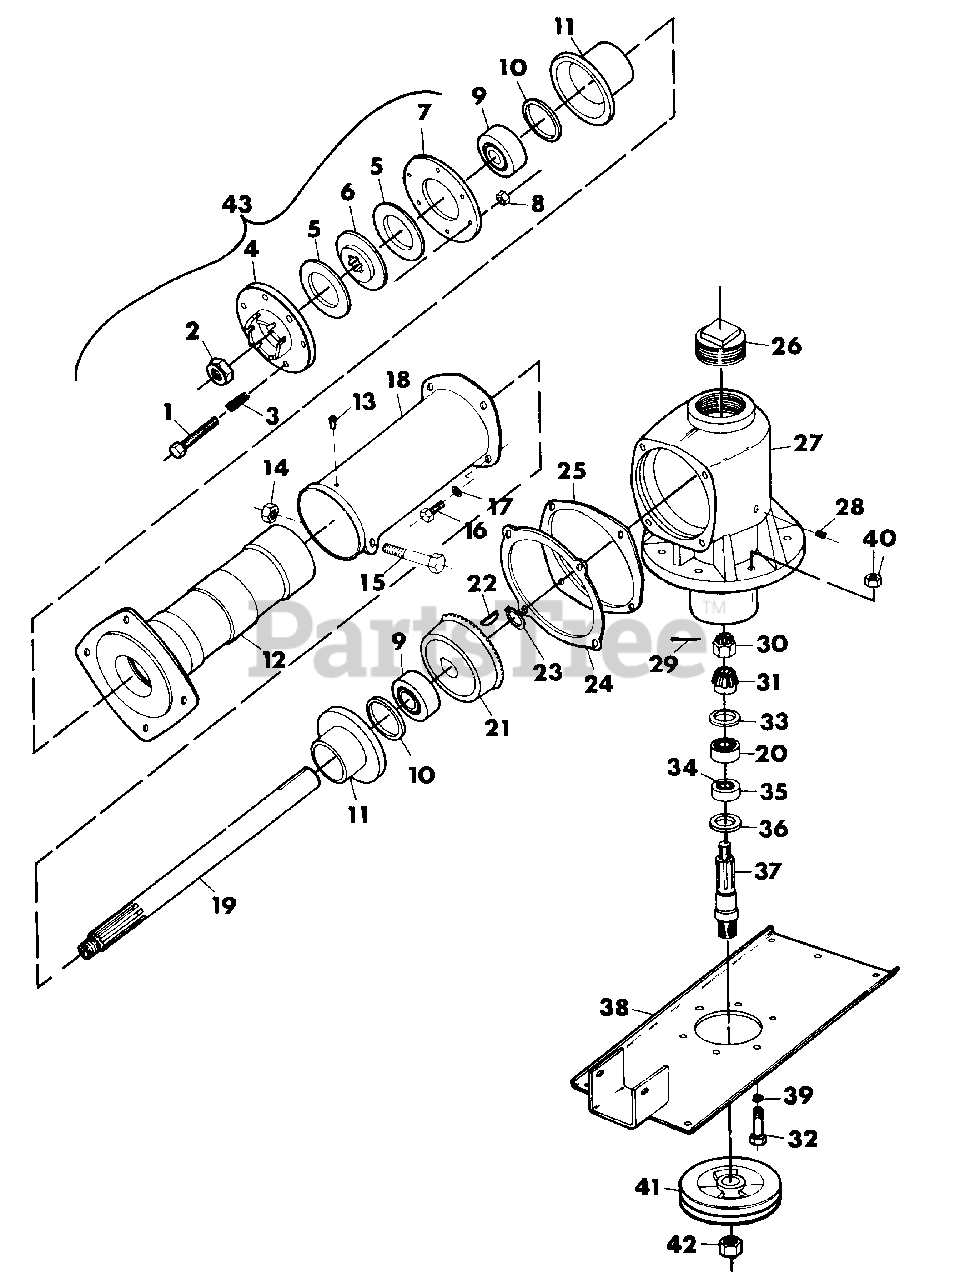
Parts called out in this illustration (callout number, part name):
1	BOLT, HEX 5/16-24X1.75
2	NUT, LOCK 5/8-18 LIGHT THIN
3	SPRING
4	PLATE, DOG
5	WASHER, FRICTION
6	PLATE, DRIVE
7	PLATE, BACK
8	NUT, JAM 5/16-24
9	BEARING, RACE
9	BEARING, CONE
10	SEAL, OIL
11	RETAINER, OIL SEAL
12	HOUSING, SHAFT
13	FITTING, LUBE 1/8
14	NUT, LOCK 1/2-13
15	BOLT, HEX 1/2-13X3.75
16	BOLT, HEX 3/8-16X1.00
17	WASHER, LOCK 3/8
18	CASTING, SWIVEL
19	SHAFT, DRIVE
20	BEARING, ROLLER RACE
20	BEARING, ROLLER CONE
21	GEAR, BEVEL
22	KEY, WOODRUFF .187X.875 HARD #11
23	RING, RETAINING
24	SHIM, GEAR .020
24	SHIM, GEAR HOUSING .005
25	GASKET
26	PLUG, PIPE 2 IN. 2/FILLER PLUG
27	HOUSING, 42 IN. MOWER GEAR
28	PLUG, PIPE 1/8 IN.
29	PIN, COTTER .094X1.25
30	NUT, SLOTTED 5/8-18
31	GEAR, BEVEL
32	BOLT, HEX SPECIAL
33	SHIM, GEAR
33	SHIM, GEAR .010
34	BEARING, ROLLER CONE
35	BEARING, ROLLER RACE
36	SEAL, OIL(DUAL LIP)
37	SHAFT, DRIVE ROTOR
38	PLATE, MOUNTING WELDMENT
39	WASHER, LOCK 1/2
40	NUT, JAM 1/2-13
41	SHEAVE, 1/2X6 DOUBLE GROOVE
42	NUT, SPECIAL
43	ASSEMBLY, CLUTCH ATTACHMENT
